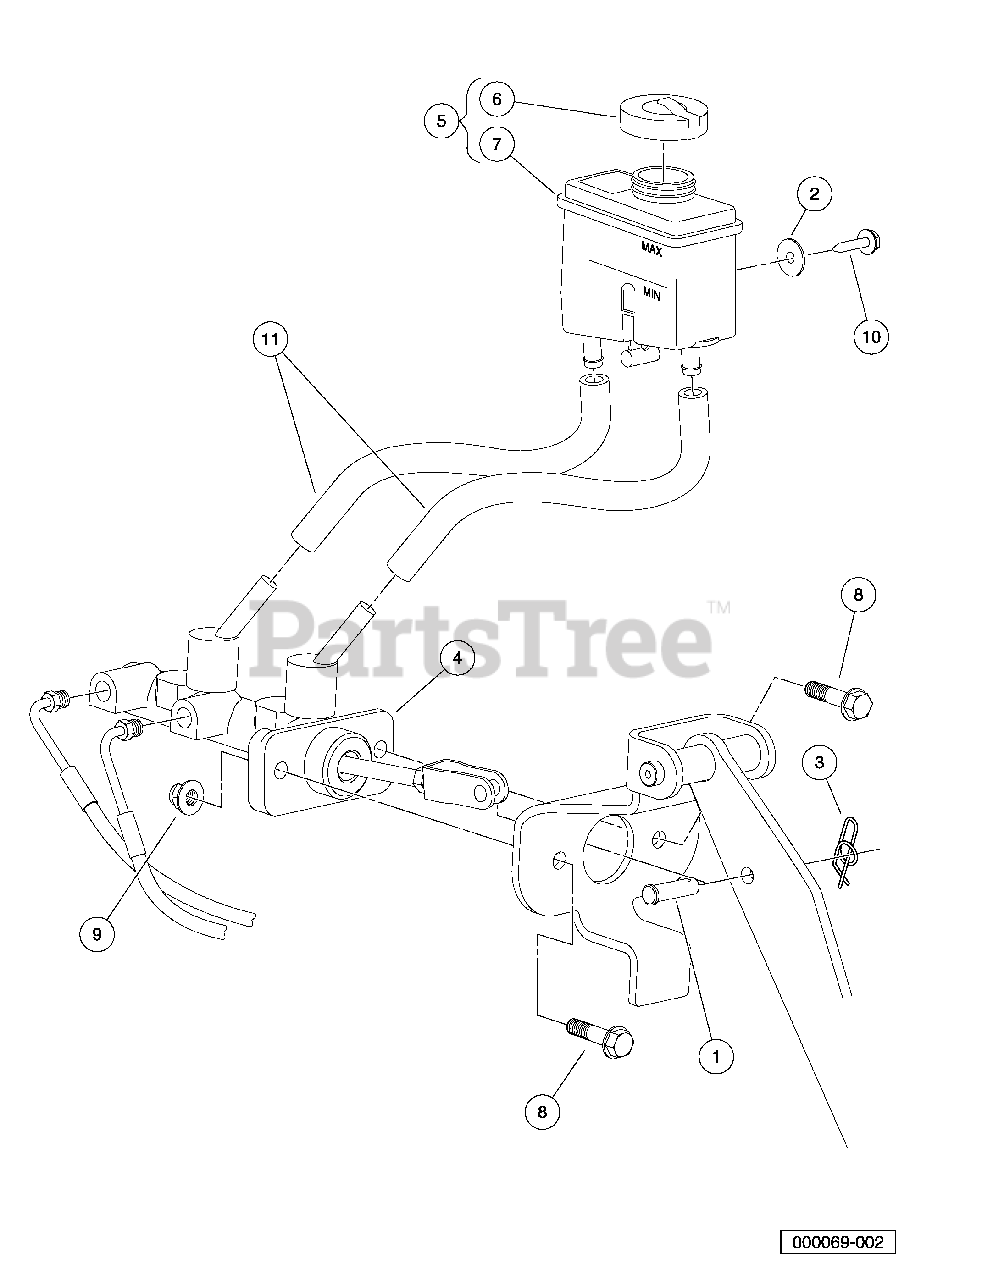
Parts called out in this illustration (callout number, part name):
1	Clevis Pin, 5/16 X 1
2	Washer, 1/4" Type B Flat
3	Pin, Rue
4	Cylinder, Master, Tandem
5	Assembly, Reservoir, Remote
6	Filler Cap Asm
7	Reservoir, Brake Fluid, Without Cap
8	Bolt Flanged Head, M8 X 1.25 X 35
9	Lock Nut, Flg M8 X 1.25 Nylon
10	Screw, #10x3.50 Ab Thd, Hex Hd
11	Hose, Reservoir, Brake Fluid
